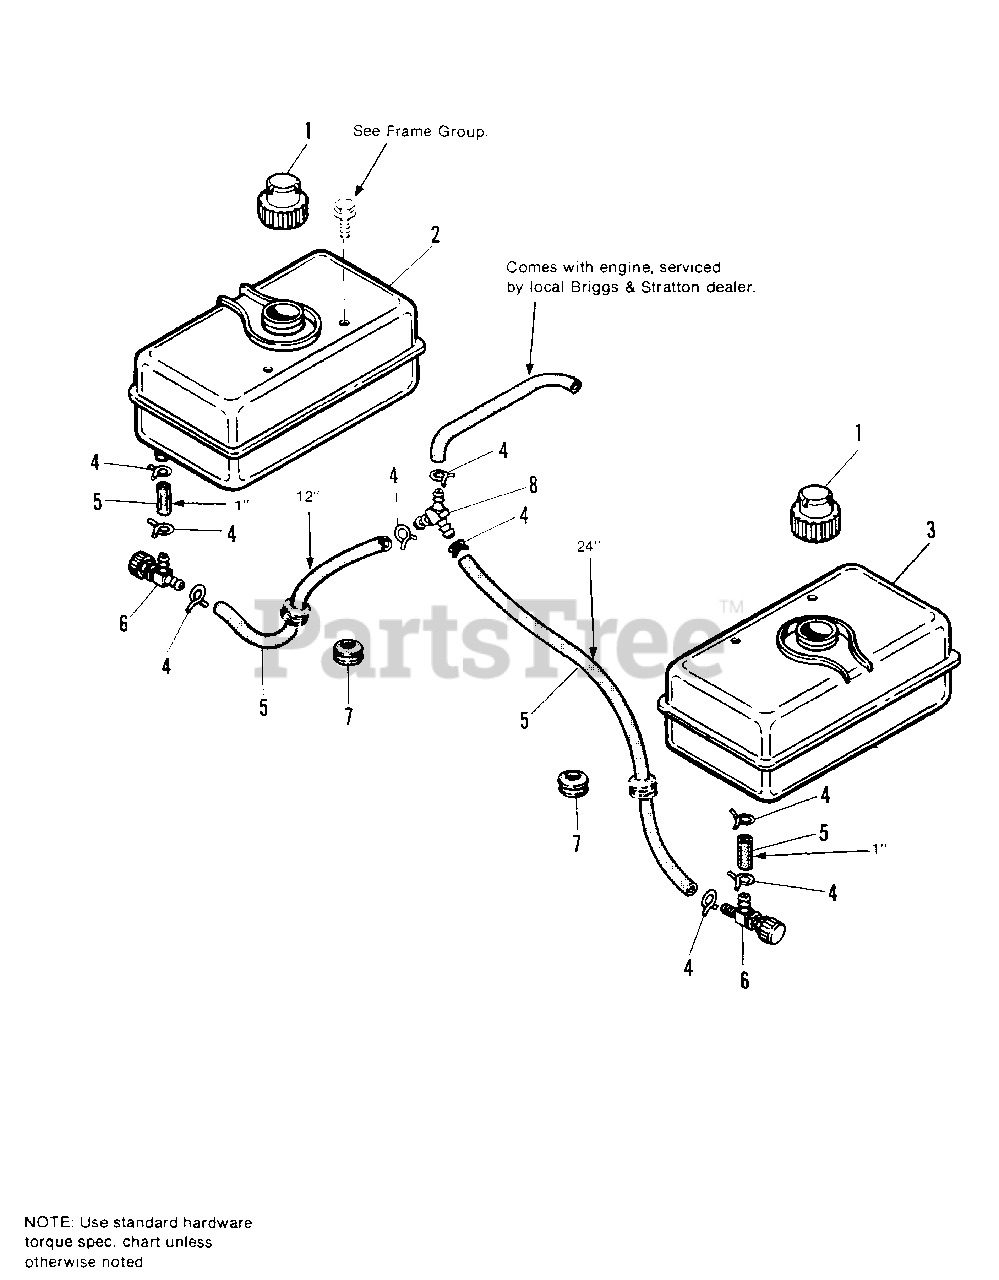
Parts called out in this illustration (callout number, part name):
1	CAP, Fuel Tank (Later Models 2-3/8" O.D.)
1	CAP, Fuel Tank (Earlier Models, 1-13/16" O.D.)
2	TANK, Fuel (R.H.) (Incl. Cap, Part No. 1702507)
3	TANK, Fuel (L.H.) (Incl. Cap, Part No. 1702507)
4	CLAMP, Hose
5	HOSE, Fuel, 45-1/2" (cut toHOSE, Fuel, Cut to 12th, see illustration)
6	VALVE, Shutoff
8	FITTING, Tee
